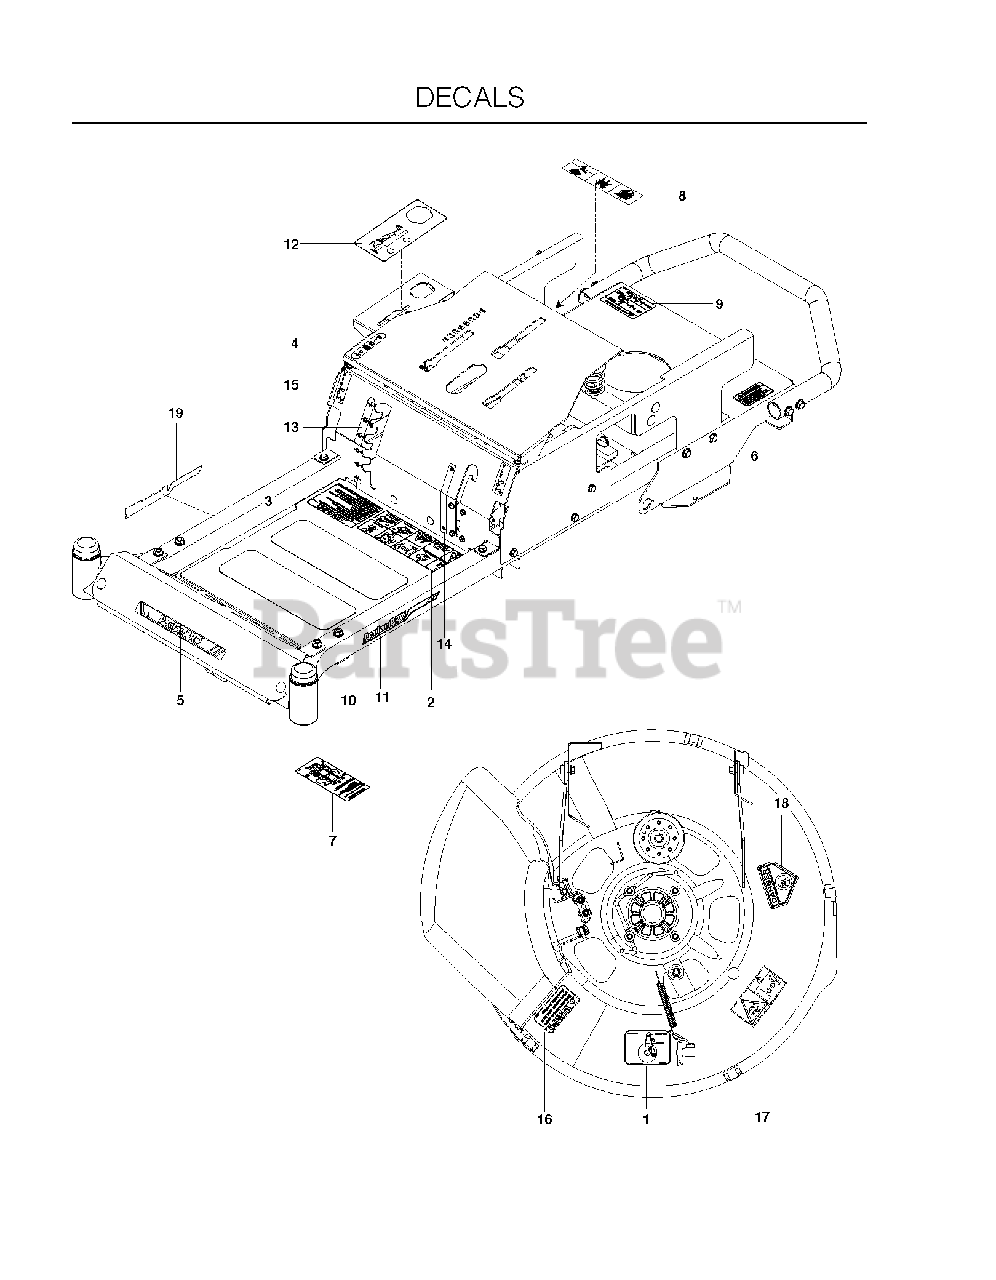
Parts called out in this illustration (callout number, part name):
1	DECAL, BELT ROUTING
2	DECAL, SAFETY WARNING
3	DECAL, WARNING
4	DECAL, PARK BRAKE
5	DECAL, POULAN, FRONT
6	DECAL, PROP. 65
7	DECAL, SERVICE
8	DECAL, BATTERY
9	DECAL, DO NOT MOUNT
10	ANTI-SKID PAD
11	DECAL, POULAN, LEFT
13	DECAL, DECK HEIGHT
14	DECAL, BLADE ENGAGEMENT
15	DECAL, MOTION CONTROL, BLK
16	DECAL, CAUTION
17	DECAL, EURO SEVERING
18	DECAL, CPSC
19	DECAL, POULAN, RIGHT
